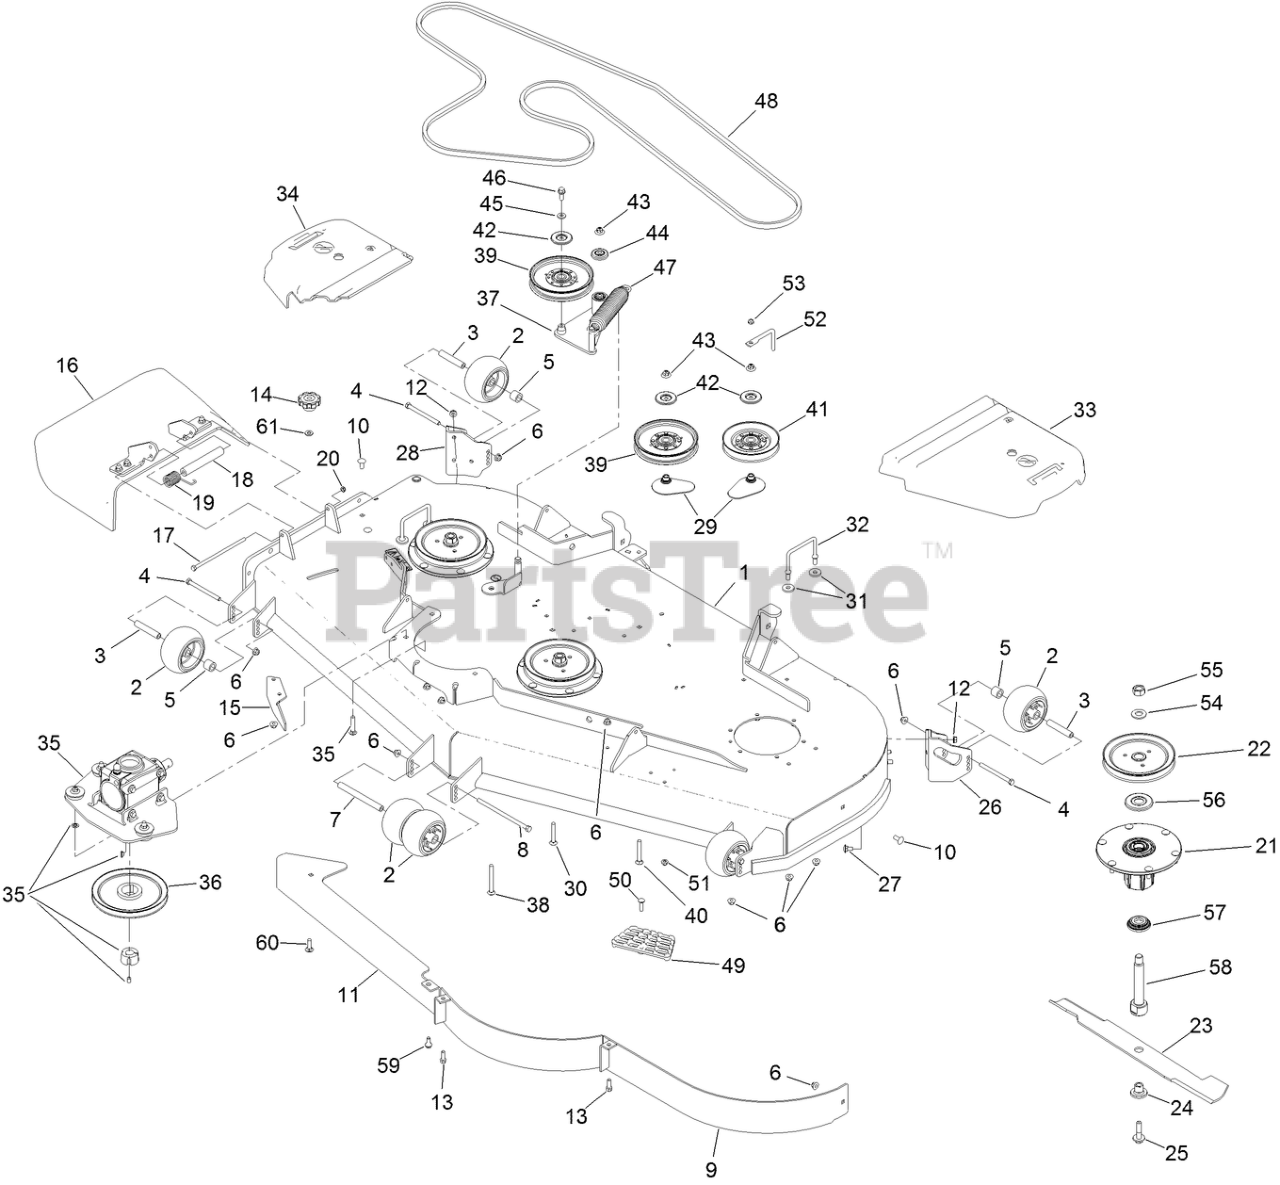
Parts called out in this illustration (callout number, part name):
1	DECK DECAL ASM
2	ROLLER-SCALP, ANTI
3	TUBE-SPANNER
4	SCREW-HH
5	TUBE-SPACER
6	NUT-HF, NI
7	SPACER-WHEEL
8	SCREW-HH
10	SCREW-CARR
11	PLATE-BAFFLE
12	NUT-HHF, WHIZ
15	BAFFLE-DISCHARGE
16	RUBBER DEFLECTOR ASM
17	SCREW-HH
18	SPACER
19	SPRING-TORSION
20	NUT-LOCK, NI
21	SPINDLE ASM
22	SHEAVE-DRIVE, BLADE
24	BUSHING-HEX
25	SCREW-SEMS
26	MOUNT-WHEEL, LH
27	SCREW-CARR
28	MOUNT-WHEEL, RH
29	SPACER-PULLEY
30	SCREW-CARR
31	WASHER
32	WIREFORM-COVER
33	COVER-BELT, LH
34	SHIELD-BELT
35	GEARBOX ASM
36	PULLEY
37	IDLER ARM ASM
38	BOLT-SHOULDER, CARRIAGE
39	IDLER-PULLEY
40	SCREW-CARR
41	IDLER V
42	SHIELD-DUST
43	NUT-FLANGE, NI
44	GUARD-TOP
45	SPACER
46	SCREW-HHF
47	SPRING-EXTENSION
48	BELT-V
49	STEP-DECK
50	SCREW-CARR
51	NUT-HF, NI
52	GUIDE-BELT
54	WASHER
55	NUT-HEX
56	GUARD-BEARING, TOP
57	GUARD-BOTTOM
58	SHAFT-SPINDLE
59	BOLT-SHOULDER
60	BOLT-CARR
61	WASHER-HARDENED
